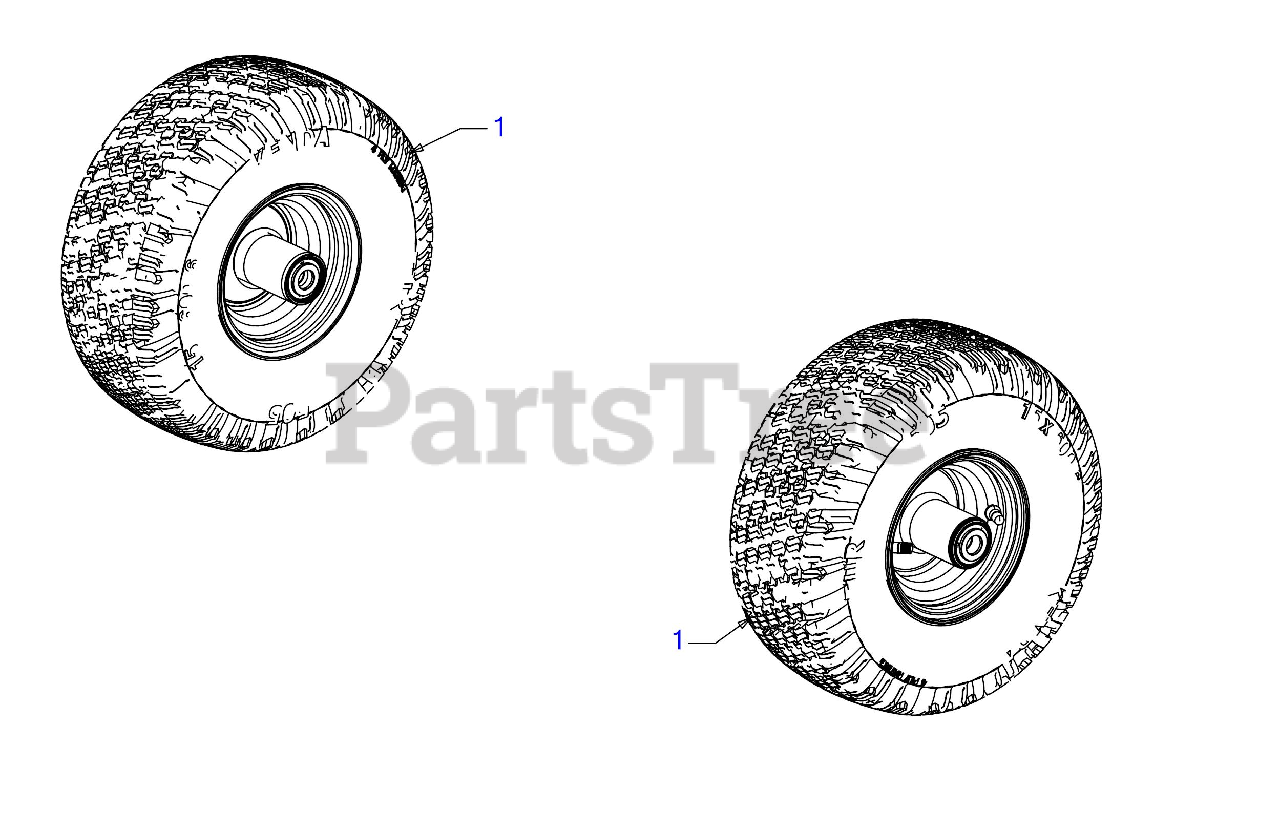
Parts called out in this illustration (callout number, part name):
1	TIRE (15x6-6)
1	FRONT WHEEL ASSEMBLY 15 x 6-6
1	SEALED BALL BEARING
